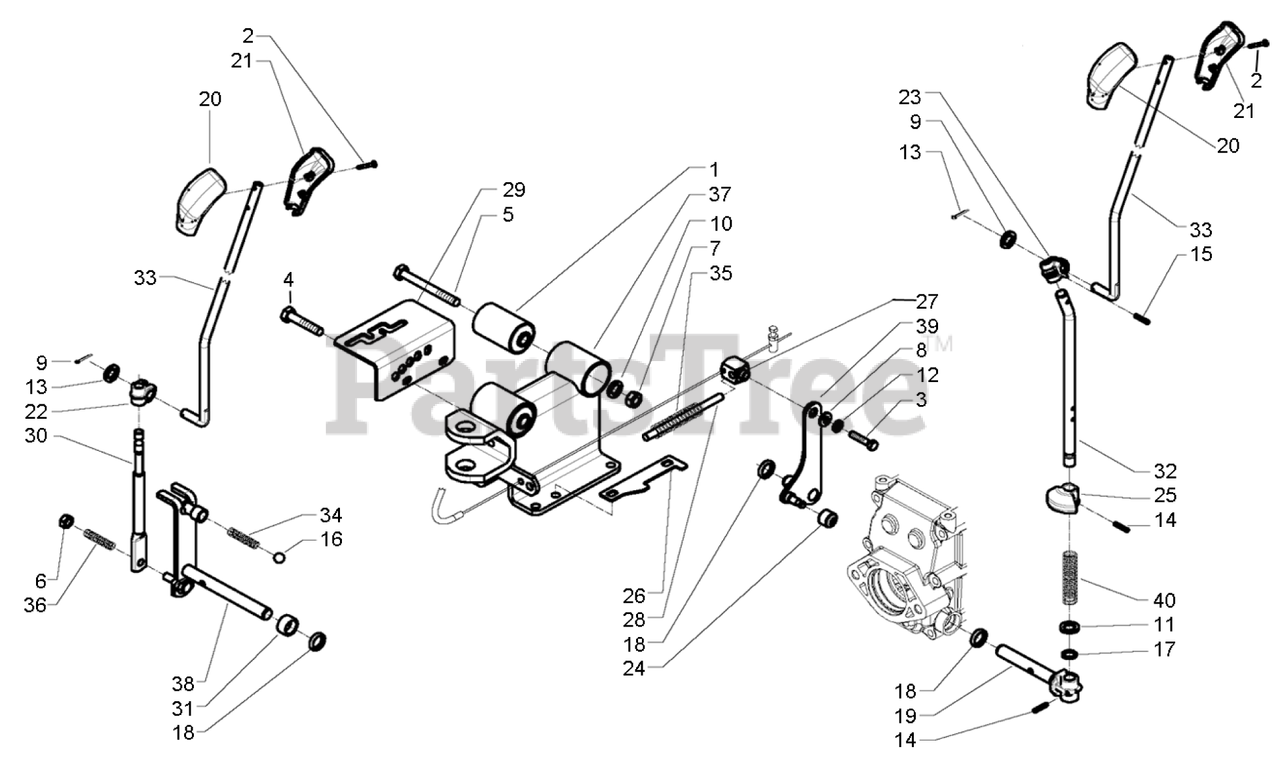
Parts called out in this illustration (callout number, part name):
1	SILENT-BLOCK 12X40X58X66
2	SCREW 3,5X25
3	SCREW TE M8X12
4	SCREW TE C/F M8X16
5	SCREW TE M12X100
6	SELFLOCK NUT M8
7	SELFLOCK NUT M12
8	WASHER M8,4X17
9	WASHER M10,5X18
10	WASHER M13X24
11	WASHER M13
12	SPRING WASHER M8,4
13	SPLIT PIN
14	ROLL PIN M4X20 SPIROL
15	ROLL PIN M4X24 SPIROL
16	BALL 15/32
17	0-RING M11.91X2.62)
18	OIL SEAL M14X22X4
22	JOINT
23	JOINT
24	ROLLER
26	STOP
27	SMALL BLOCK
28	GUIDE PIN
29	GEAR SELECTOR
30	COMMAND LEVER
31	SPACER
32	PTO LEVER
33	PULL ROD
34	SPRING
35	SPRING
36	SPRING
37	SUPPORT
38	GEAR LEVER
39	LEVER
40	SPRING DM.15X70
